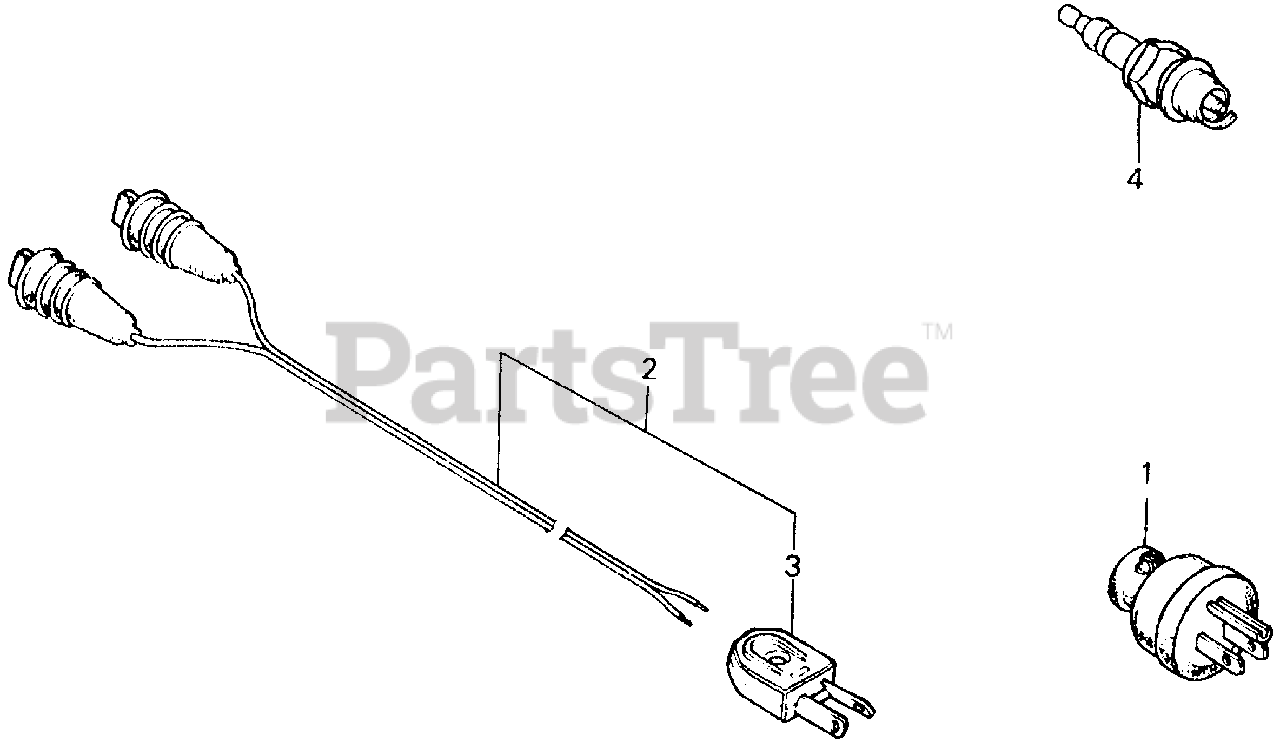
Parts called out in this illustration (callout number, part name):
1	PLUG ASSY., RECEPTACLE
2	WIRE ASSY., CHARGE
3	PLUG ASSY., RECEPTACLE (NOT AVAILABLE)
4	SPARK PLUG (BPMR4A-10) (NGK)
4	SPARK PLUG (BPMR6A-10) (NGK)
